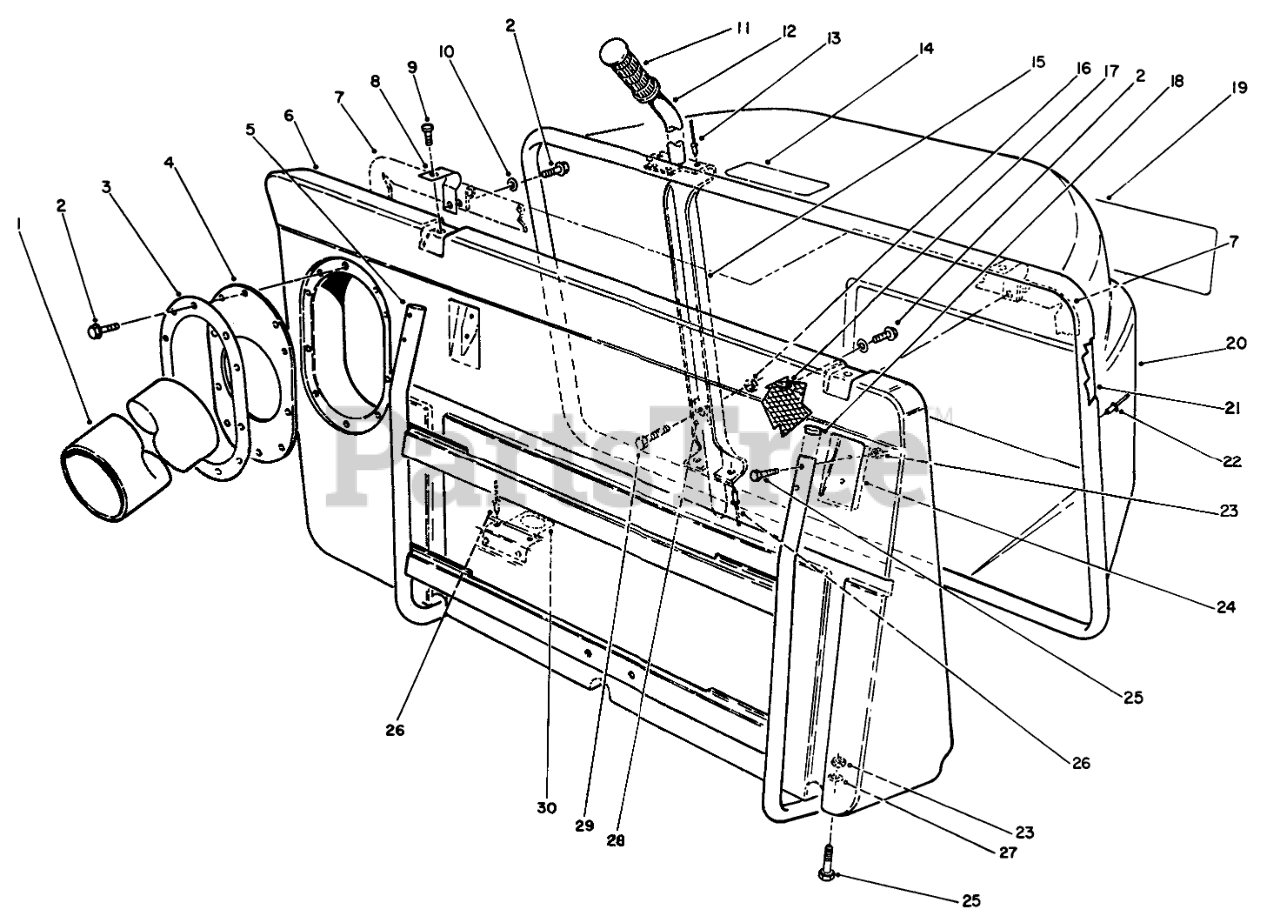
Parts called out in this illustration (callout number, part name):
1	Duct (Ref.)
2	Screw-Self Tapping
3	RING-RETAINING
4	Seal (Ref.)
5	Frame
6	BAG-FRONT
7	SEAL-BAG
8	Bracket-Hinge
9	Screw
10	WASHER-FLAT
11	GRIP-HANDLE
12	HANDLE-DUMP
13	Rivet-Pop
14	Decal Warning
15	Channel-Dump Handle
16	NUT-LOCK, NI
17	Screen Bag
19	DECAL - TORO
20	BASKET-GRASS
21	Frame-Grass Basket
22	NUT-LOCK
23	NUT-LOCK, NI
24	Plate-Backup
25	SCREW-HH
26	RIVET-BLIND
27	Washer
28	GUIDE-HANDLE, DUMP
29	SCREW-HH
30	Latch
